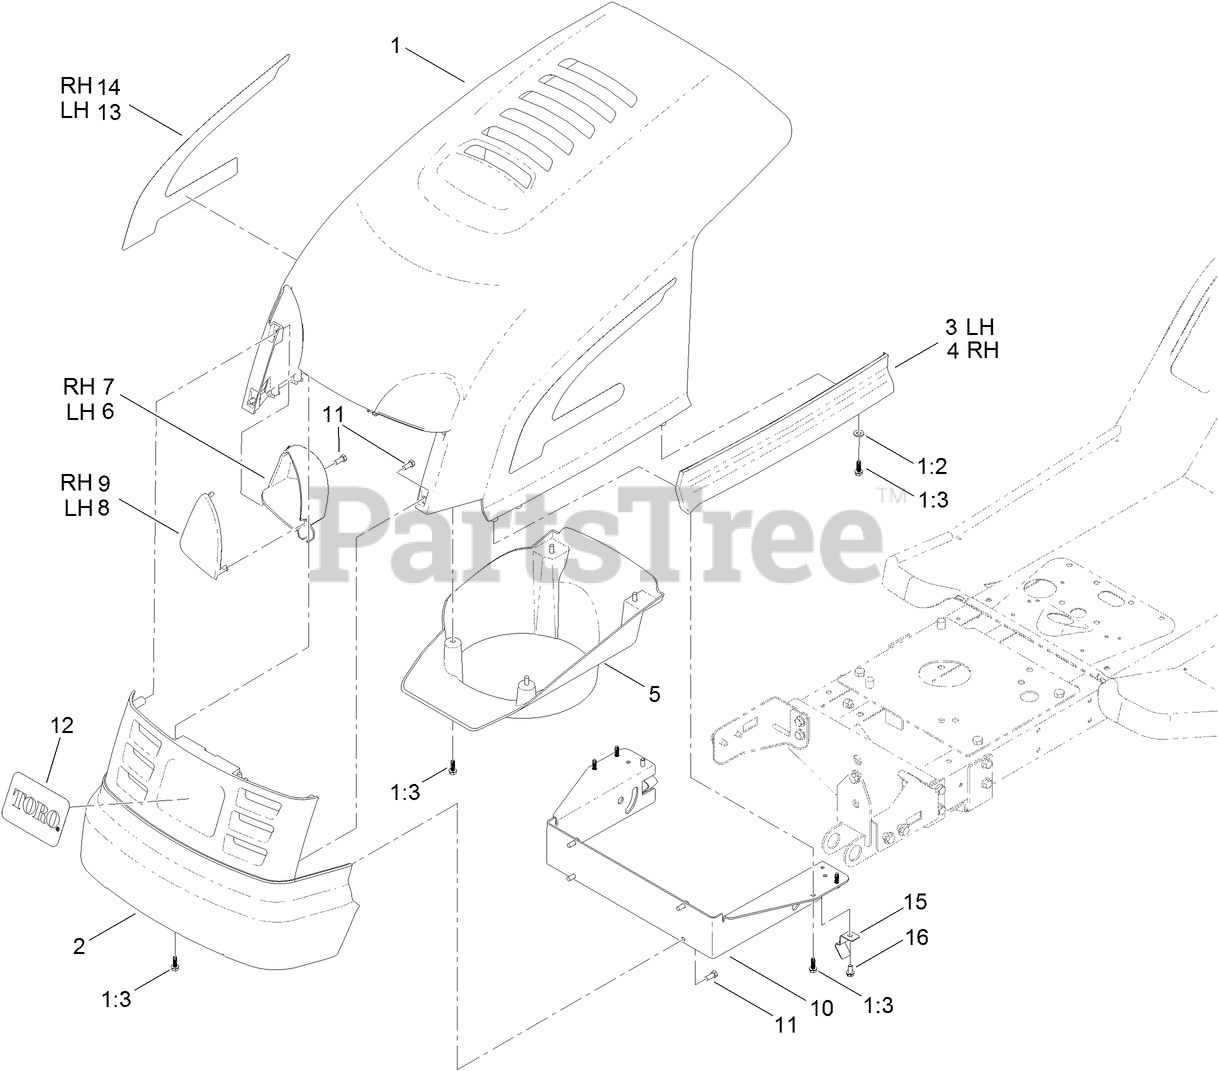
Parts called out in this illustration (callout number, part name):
1	HOOD KIT
1:2	WASHER-FLAT
1:3	SCREW-SELF TAPPING
3	TRIM-HOOD, LH
4	TRIM-HOOD, RH
5	DUCT-AIR, HOOD
6	REFLECTOR-LH
7	REFLECTOR-RH
8	LENS-LH
9	LENS-RH
10	BRACKET-MOUNTING, HOOD
11	SCREW-PLASTITE
13	DECAL-HOOD, LH
14	DECAL-HOOD, RH
15	LATCH-HOOD
16	SCREW-HWH
